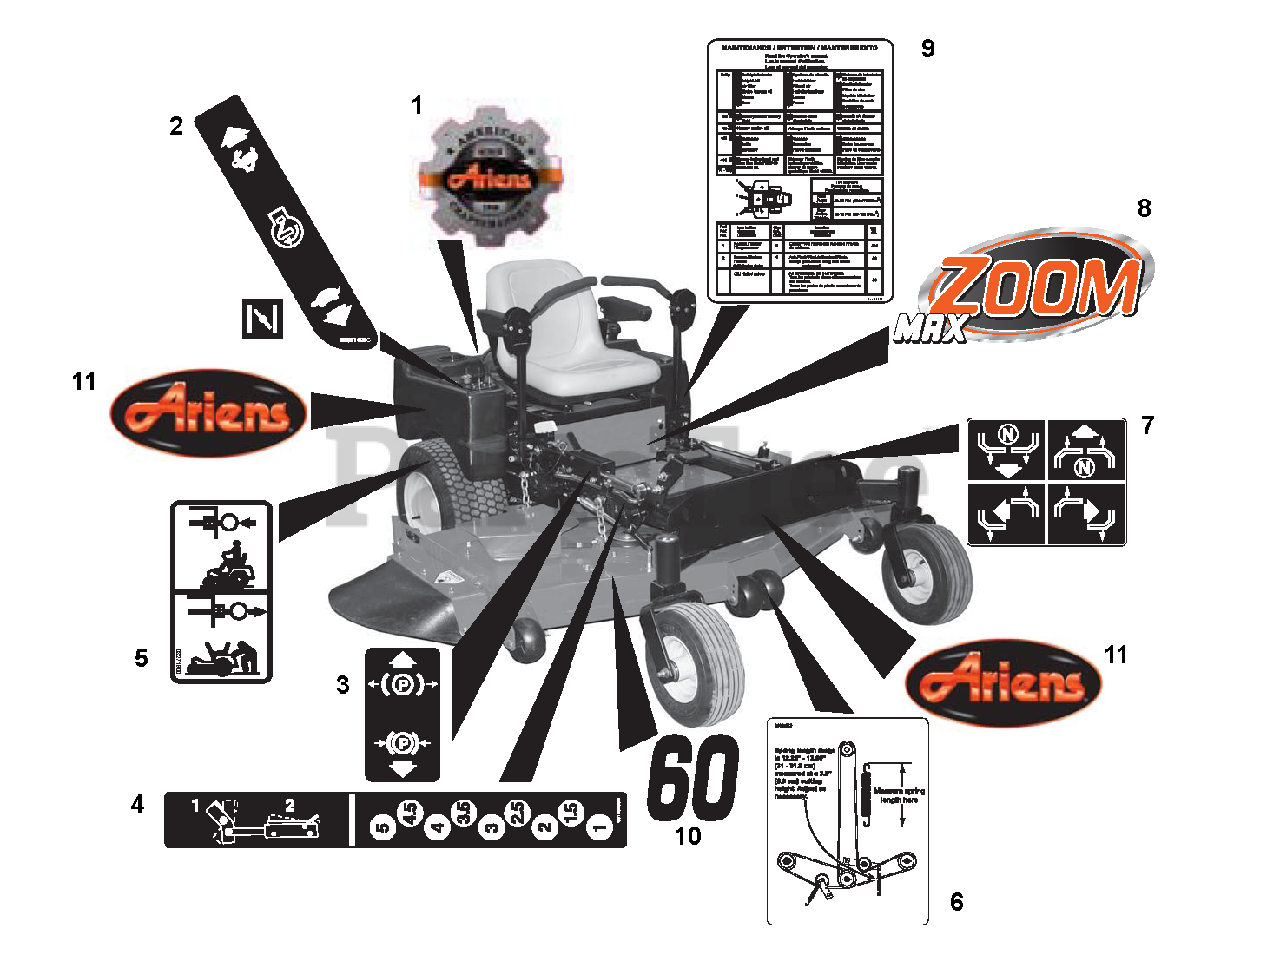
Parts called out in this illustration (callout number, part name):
1	Decal, Ariens Heritage Small
2	DECAL, SPEED CONTROL
3	DECAL, PARKING BRAKE LEVER
4	DECAL, HEIGHT OF CUT COMPACT-Z
5	DECAL, TRANSMISSION DISCONNECT
6	DECAL, BELT ROUTING
7	DECAL, INSTRUCTIONAL-STEERING
8	DECAL, MAX ZOOM
9	DECAL-MAINTENANCE INSTRUCTIONS
10	DECAL, 60"
11	DECAL, ARIENS JEWEL
